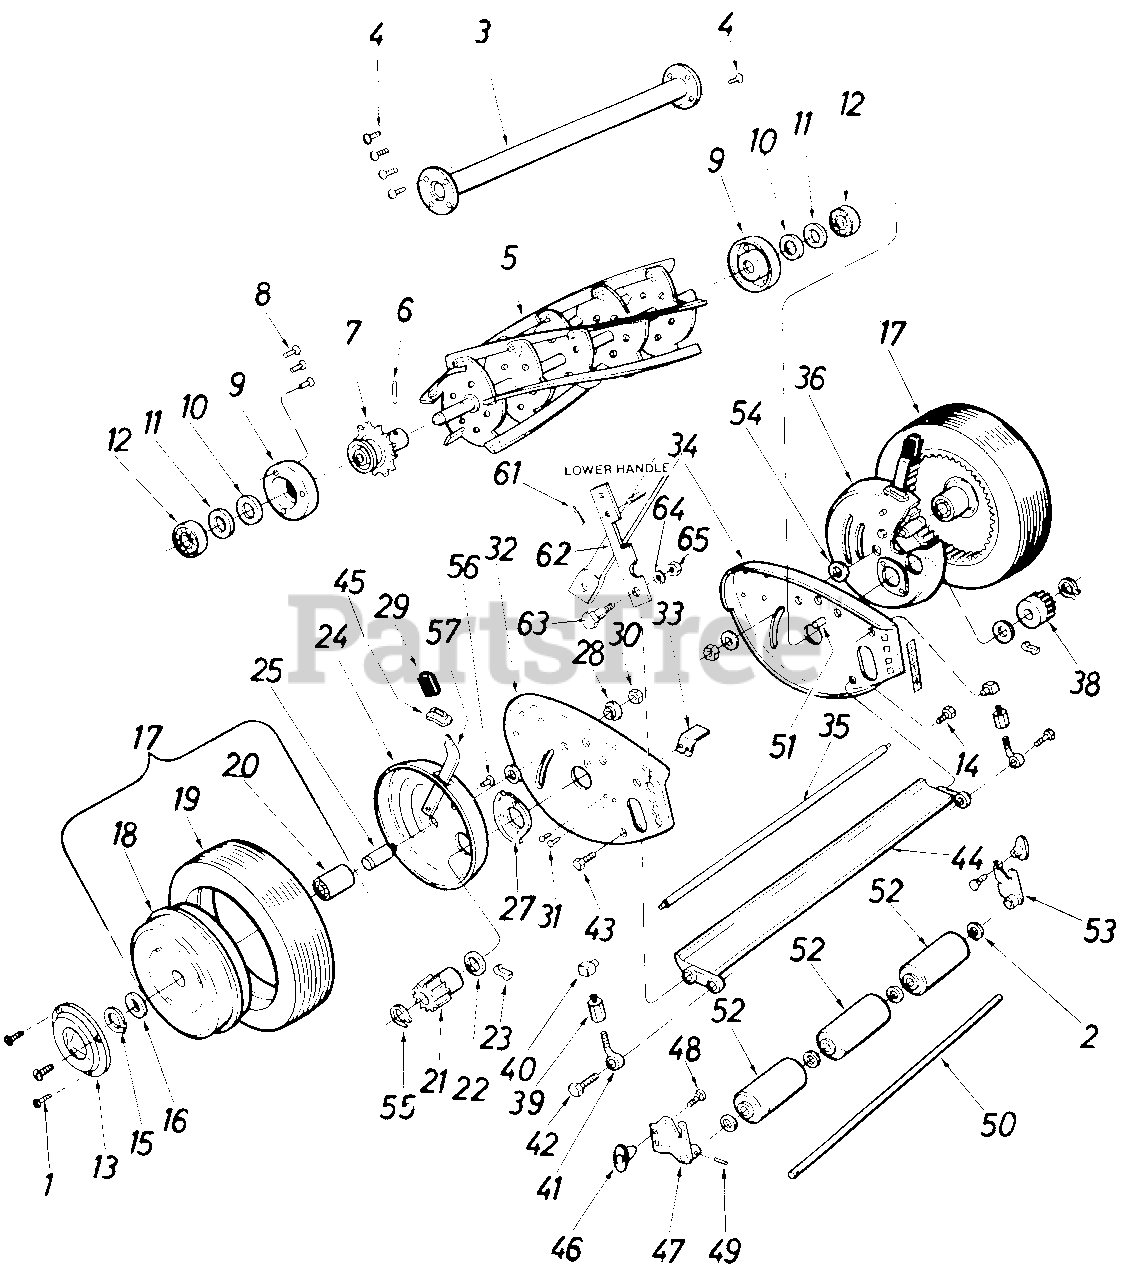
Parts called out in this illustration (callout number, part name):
1	Ph. Hd. Scr. #10-32 x .62" Lg.*
2	Roller Washer
3	21" Spacer Tube Ass'y.
4	Rivet-3/16 x 3/8"*
5	21" Reel Ass'y.
6	Roll Pin
7	Sprocket Anti-Wind Cup, and Hub Ass'y.
8	Rivet 3/16 x 13/32"*
9	Retainer
10	Felt Washer
11	Felt Retainer
12	Beari ng
13	H u b Cap
14	Scr.-Cutter Bar L.H. Thd.
15	Retaining Ring
16	Washer
17	Wheel Ass'y.-Comp.
18	Wheel Ass'y. w/Bearing
19	Tire 10.25 x 2.50
20	Bearing
21	Pinion Gear-R.H.
22	Felt Washer
24	Gear Housing-L.H.
27	Retainer
28	Bushing
29	Wheel Adj. Knob
30	Hex Lock Nut
31	Hex Sems Scr. 10-32 x .375" Lg. *
32	End Plate w/Trunnions
33	Scraper
34	End Plate w/Trunnions
35	End Plate Spacer
36	Gear Housing
38	Pinion Gear
39	Turnbuckle Nut
40	Trunnion
42	Screw
43	Scr.-Cutter Bar-R.H. Thd.
44	21" Cutter Bar Ass'y.
45	Dust Cover
46	Roller Adj. Knob
47	Rol ler Brkt. Ass'y.-L.H.
48	Hex Scr. 5/16-18 x .62" Lg.
49	Roll Pin
50	Roller Shaft
51	Trunnion
52	Roller
53	Rol ler Brkt. Ass'y.-R. H.
54	Washer
55	Retaining Ring
56	Hex Scr. #10-32 x .375" Lg.
57	Spring and Trunnion Ass'y.
61	Internal Cotter Pin
62	Handle Brace
63	Shld. Bolt 5/16-18 Thd.
64	L-Wash. 5/16" Scr.
65	Hex Nut 5/16-18 Thd.
